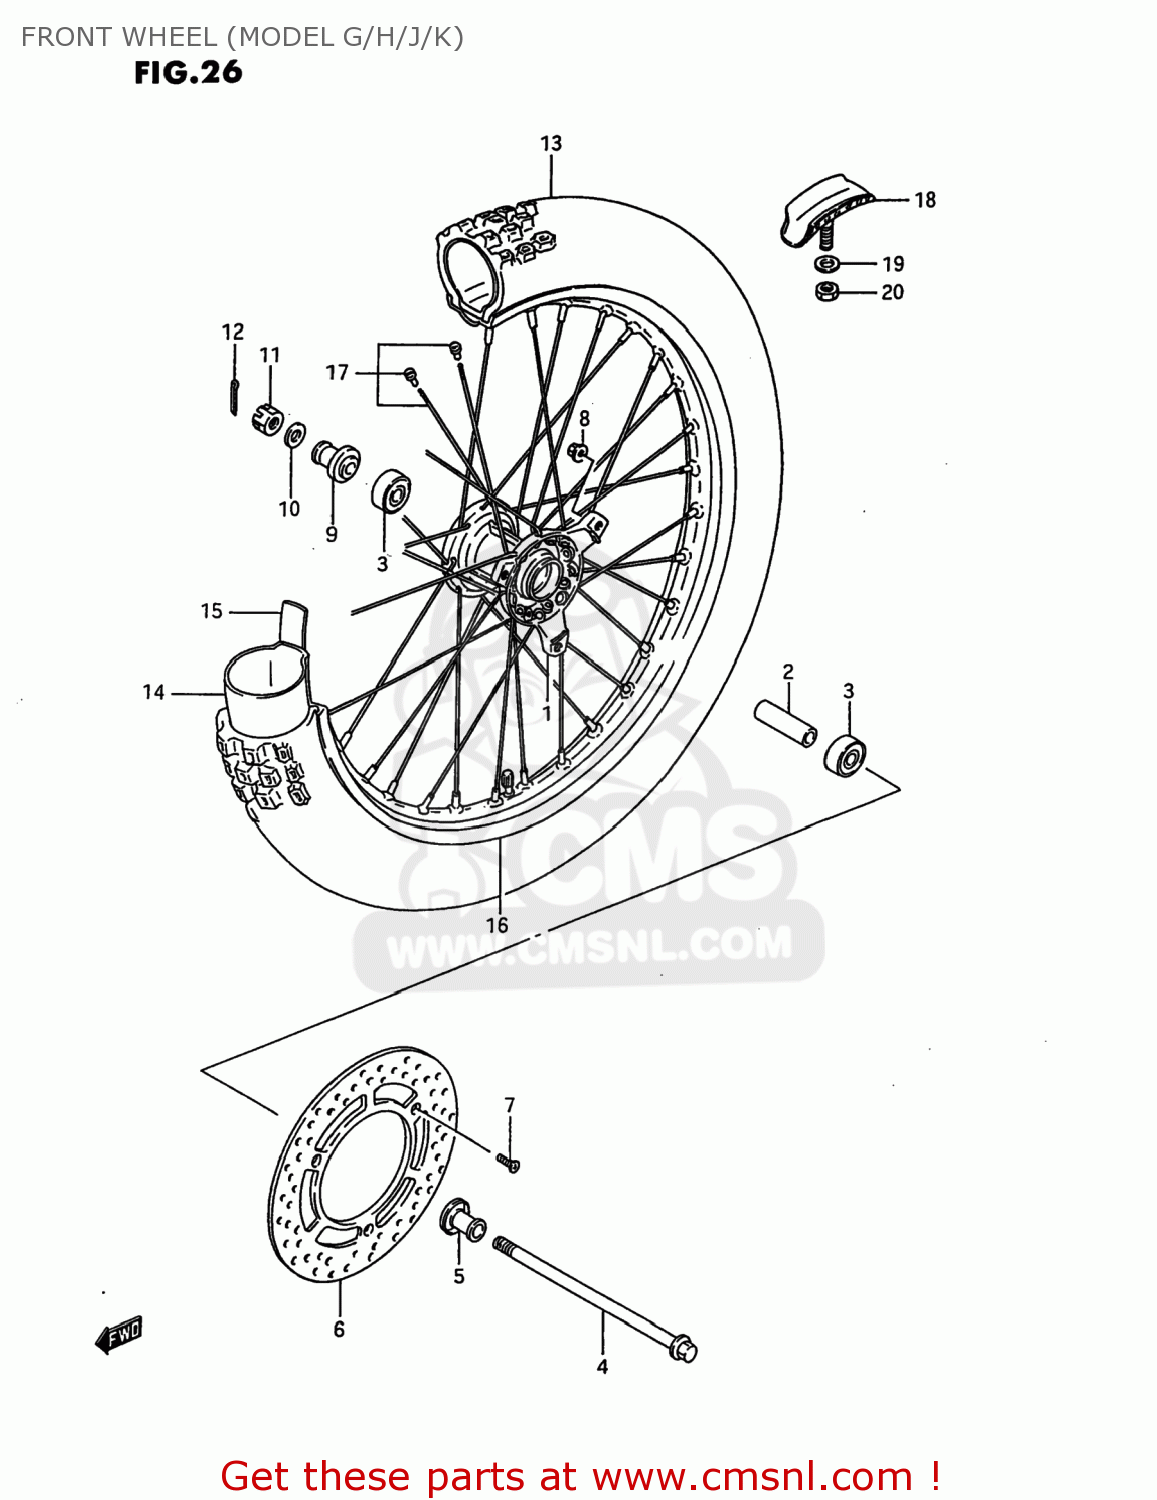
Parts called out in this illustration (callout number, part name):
1	HUB,FRONT
2	SPACER (10.4X15X52)
3	BEARING(10X30X9)
4	AXLE,FRONT
5	SPACER,FRONT AXLE,RIGHT
6	DISC,BRAKE
7	SCREW(6X22)
8	NUT
9	SPACER,FRONT AXLE,RIGHT
10	WASHER
11	NUT
12	PIN 20X20
13	TIRE,FRONT
14	TUBE,INNER (IRC)
15	PROTECTOR,WHEEL,INNER
16	RIM,FR WHEEL(1.40X17)
17	SPOKE SET,FR WHEEL
18	STOPPER,BEAD
19	WASHER
20	NUT
